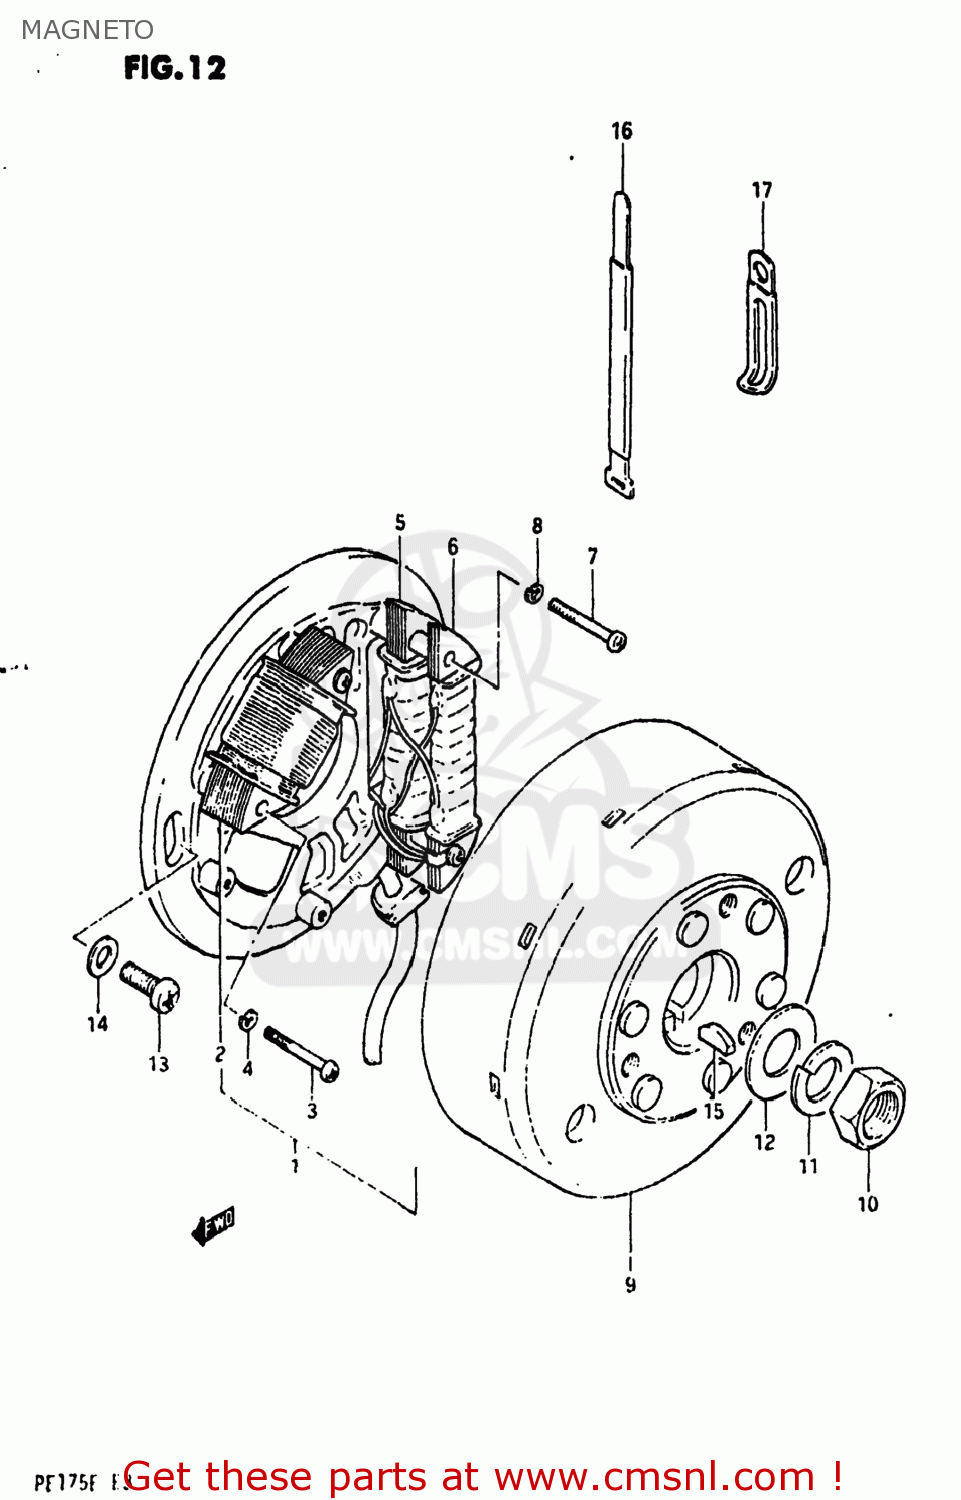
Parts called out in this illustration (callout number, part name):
1	STATOR ASSEMBLY
2	COIL,LIGHTING
3	SCREW (4X30)
4	LOCK WASHER
5	COIL
6	COIL,PRIMARY
7	SCREW (4X30)
8	LOCK WASHER
9	ROTOR ASSEMBLY
10	NUT (10MM)
11	LOCK WASHER
12	WASHER
13	SCREW
14	WASHER
15	KEY 4MM
16	CLAMP L:110
17	CLAMP
